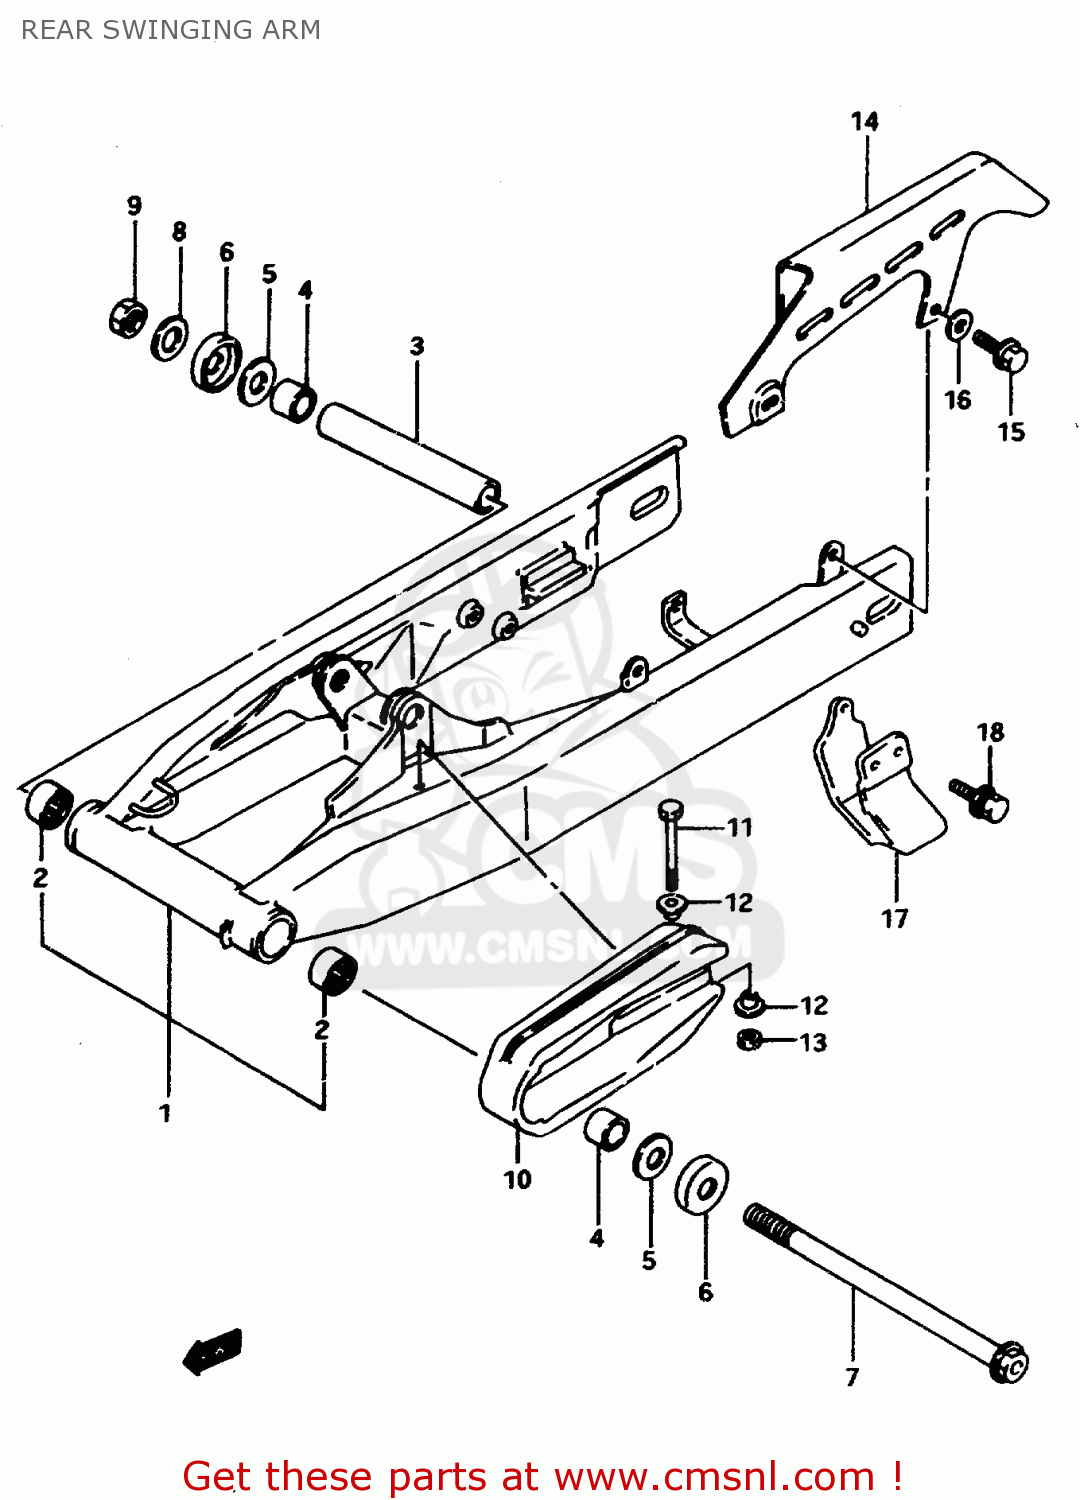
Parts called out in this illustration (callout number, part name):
1	SWINGING ARM ASSY, REAR (SILVER)
2	BEARING(22X29X20)
3	SPACER,RR SWGARM PIVOT CTR
4	SPACER,RR SWGARM PIVOT
5	WASHER
6	SEAL,RR SWGARM PIVOT DUST
7	SHAFT,RR SWINGINGARM PIVOT
8	WASHER, FIXED DRIVE FACE
9	NUT 16MM
10	BUFFER,CHAIN TOUCH DEFENSE
11	BOLT,CHAIN TOUCH DEFENCE,FTG
12	WASHER
13	NUT
14	CASE,CHAIN
15	BOLT
16	WASHER
17	GUIDE,CHAIN
18	BOLT(6X16)
